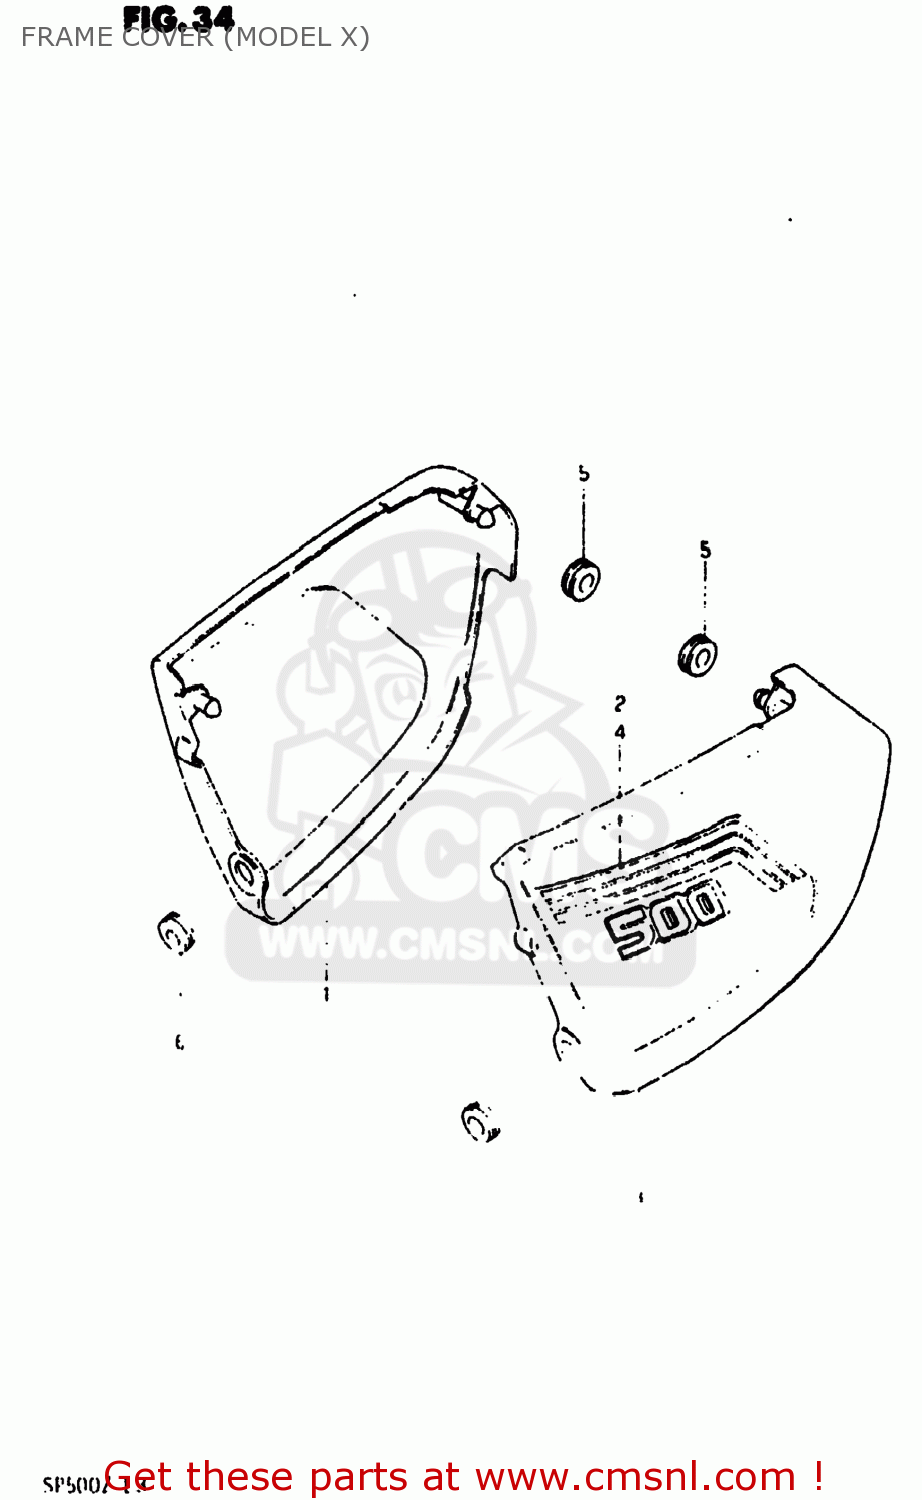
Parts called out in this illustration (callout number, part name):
1	COVER,FRAME,RIGHT
2	TAPE,FRAME COVER,RIGHT
3	COVER,FRAME,LEFT
4	TAPE,FRAME COVER
5	CUSHION
6	CUSHION
